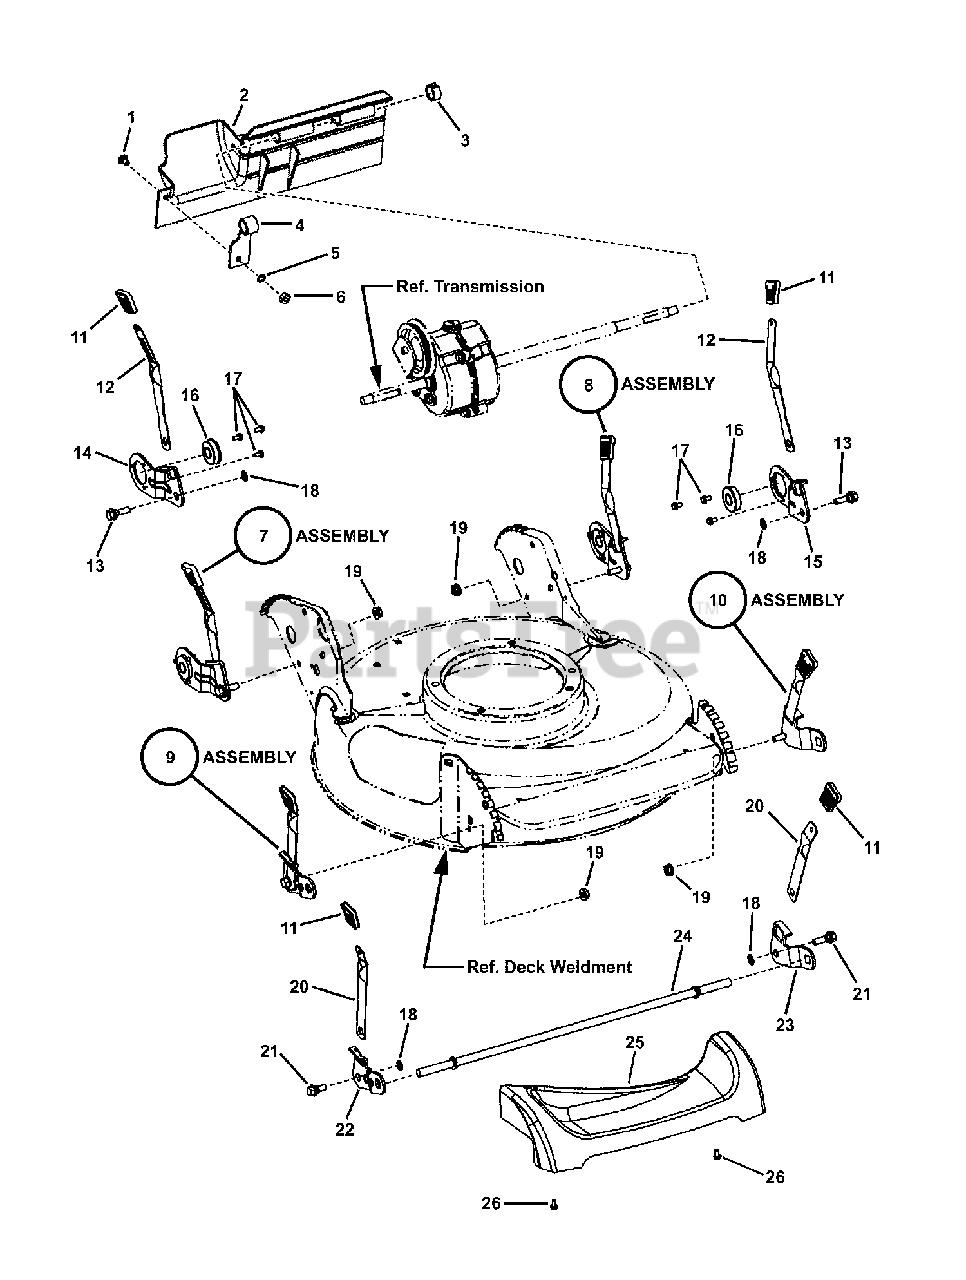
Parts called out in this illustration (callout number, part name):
1	BOLT, 1/4-20 x 1/2" Short Neck Carriage GR 5
2	FOOT GUARD, P21 Euro, Long
3	RING, Split (Black)
4	SUPPORT, Foot Guard
5	WASHER, 1/4" Internal Tooth Lock
6	NUT, 1/4-20 Hex, GR 5 or B
7	ASSY, Wheel Arm, Right Rear (S.P.)
8	ASSY, Wheel Arm Left Rear Long SP21S
9	ASSEMBLY, Right Wheel Arm
10	ASSEMBLY, Left Wheel Arm
11	GRIP, Height Latch - Black (1.3" Wide)
12	LATCH, Height Adjusting (long)
13	BOLT, 5/16-18 x 1" Hex Washer Face Shoulder
14	ARM, Wheel, Right Rear
15	ARM, Wheel, Left Rear
16	BEARING, 9/16" I.D.
17	SCREW, #10-32 x 3/8" Hex Washer Self-Tap
18	RETAINER, 5/16" Bolt
19	NUT, 5/16-18 Hex Flange Lock, GR 5
20	LATCH, Height
21	BOLT, 5/16-18 x 3/4" Hex Washer Face Shoulder
22	WHEEL ARM, R.H. Front (Round Hole)
23	WHEEL ARM, L.H. Front (Square Hole)
24	AXLE, 21" (3/8-16 thread- both ends, 20.62" long)
24	AXLE, 21" (7/16-20 thread- both ends, 20.44" long)
25	COVER, Front 21" walk
26	SCREW, Round Washer Head Torx, Hi-Lo
